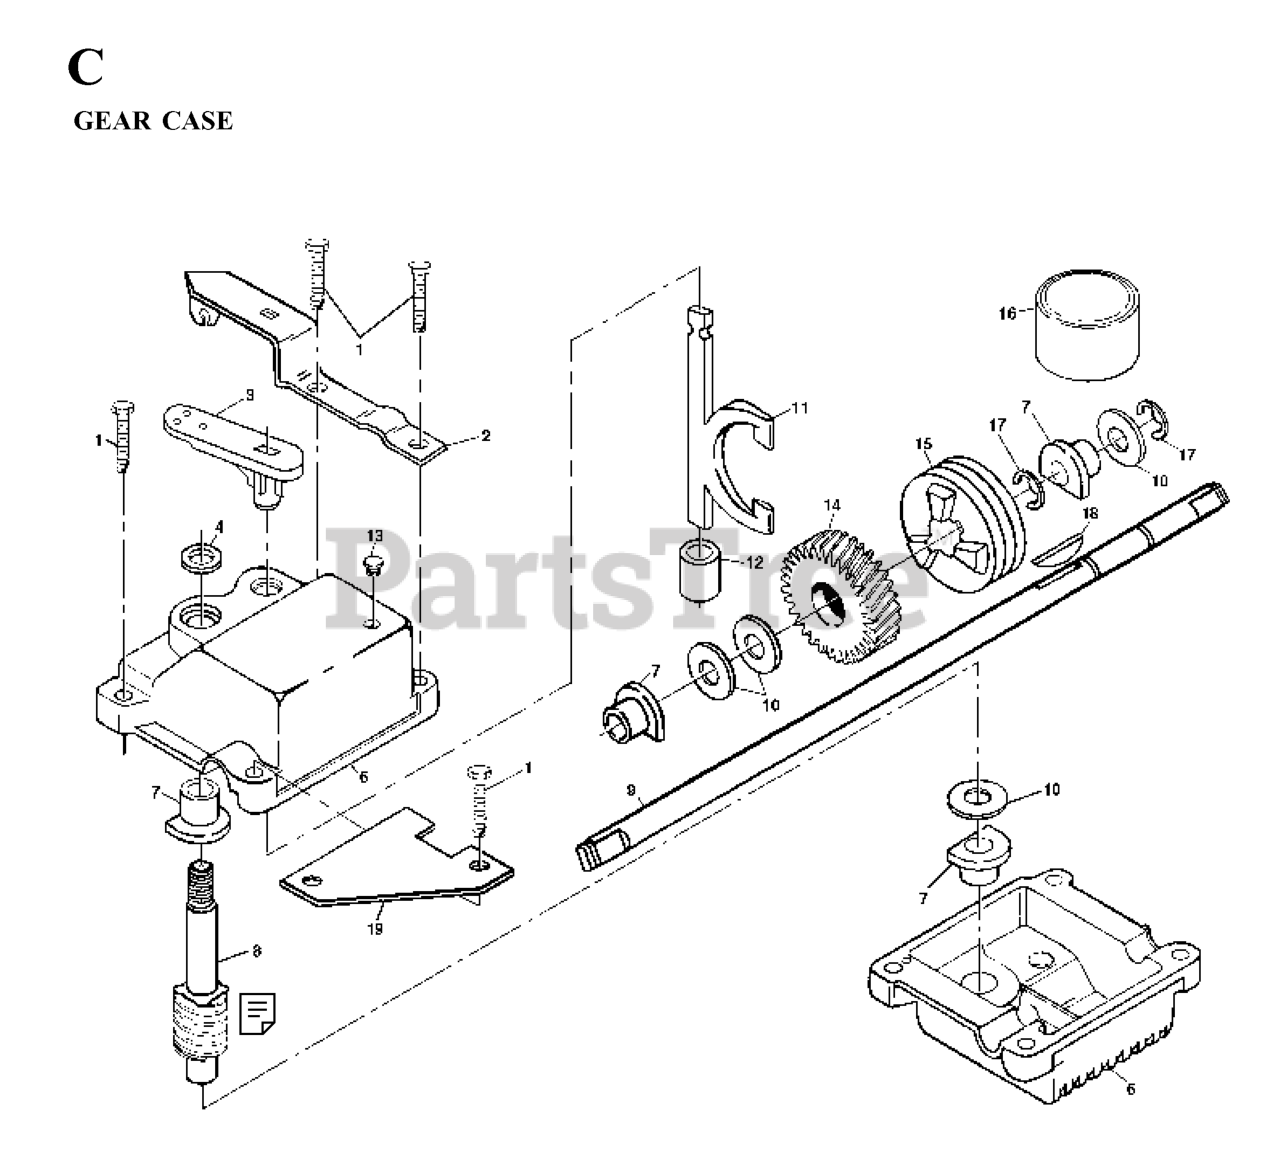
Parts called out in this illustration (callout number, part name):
1	SCREW
2	BRACKET
8	WORM SHAFT
9	DRIVE SHAFT, 20-5/8"
10	THRUST WASHER
11	YOKE.VIBRATORY FINISH.
13	PLUG.AUGER.GEAR.BOX.SNOW
14	GEAR.HELICAL
15	CLUTCH JAW
16	GREASE
18	HI PRO KEY
19	BRACKET SPRING
20	WOODRUFF KEY
21	WORM
